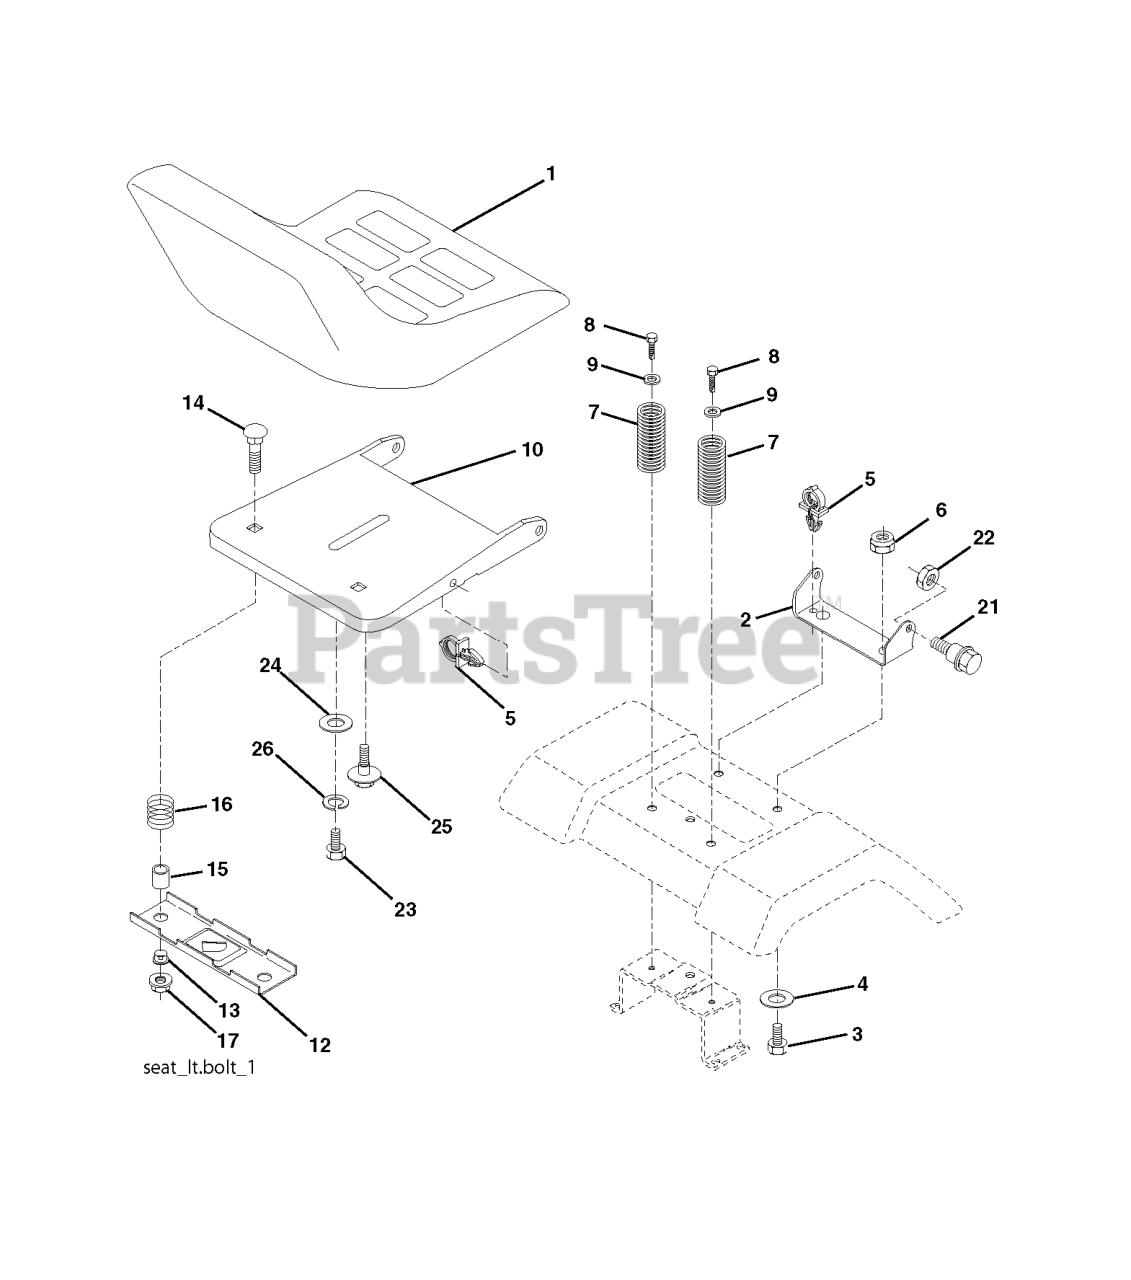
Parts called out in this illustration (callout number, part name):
1	SEAT.XG090.BLK.KB/BLT.NO-LOG
2	SEAT PIVOT BRKT
3	BOLT, HEX 3/8-16X1
6	NUT
7	SPRING COMPRESSION
8	SCREW 3/8-16X1
9	WASHER
10	PAN.ASM.SEAT.1SLOT
12	BRKT.MNTNG.SWITCH.SEAT.BLACK
14	BOLT.ROUND.HEAD.SQUARE.NECK
15	SPACER SPLIT 28X.96
17	NUT T
21	BOLT.SHOULDER.5/16-18
22	NUT.71038.31-18.HEX.NYLOCK
23	BOLT.HEX.BLACK
25	BOLT,SHOULD
26	LOCKWASHER
